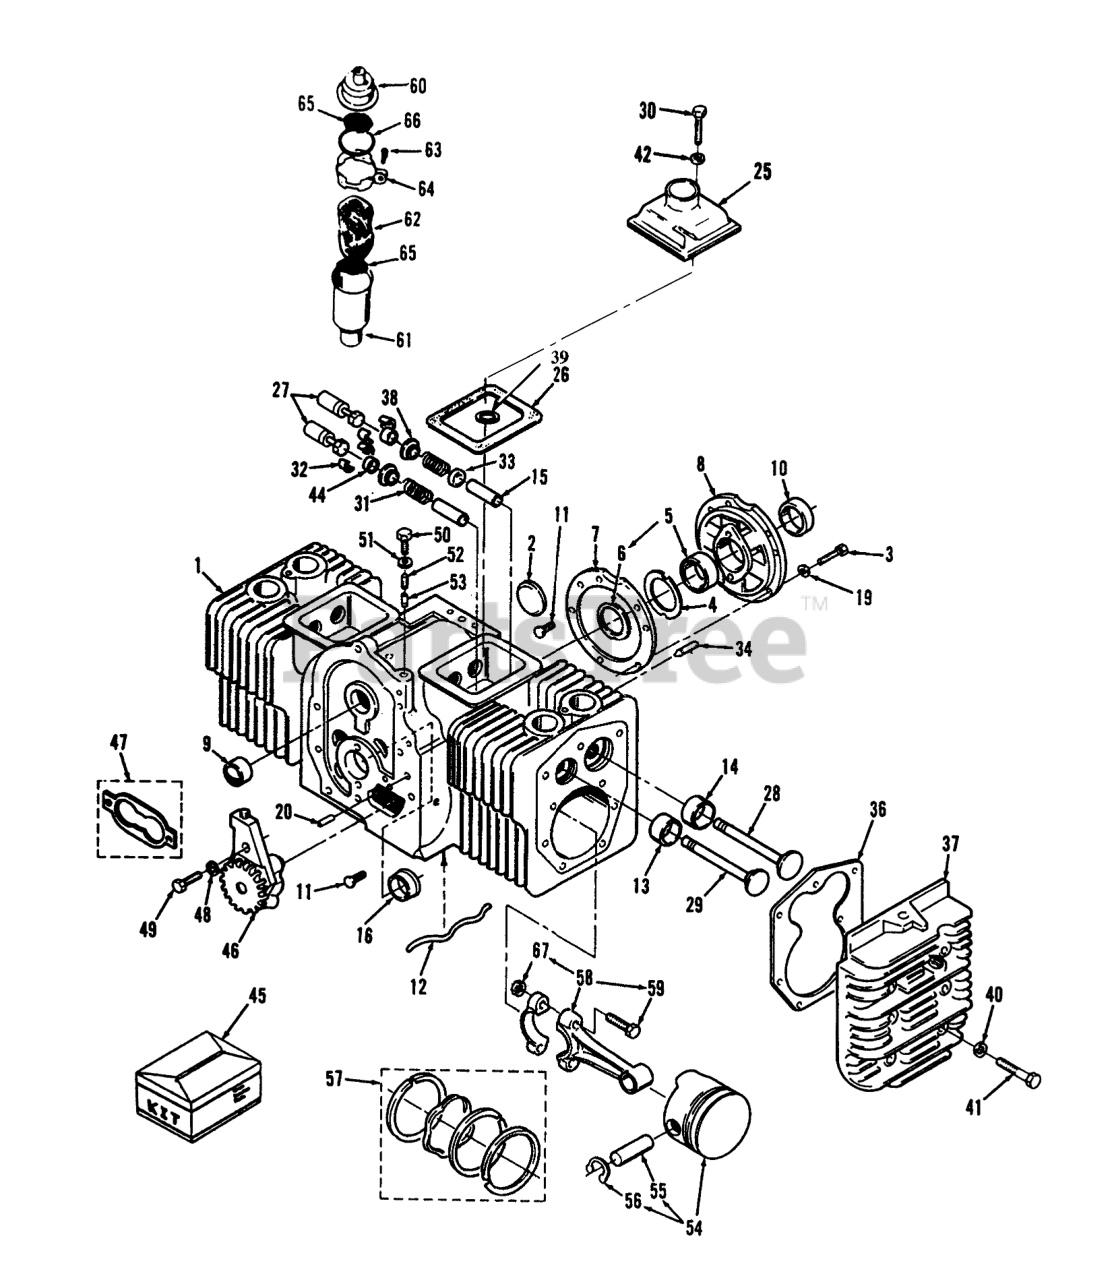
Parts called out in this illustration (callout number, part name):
1	CYLINDER BLOCK
2	Plug
3	Bolt 3/8-16x 1-1/4
5	Bearing-Crankshaft, Rear(Includes Thrust Washer)
6	Thrust Washer
7	GASKET
8	PLATE-BEARING, REAR
9	Camshaft Brg
10	Oil Seal
11	Screw
12	Oil Tube
13	Insert-Valve Seat, Exhaust
14	Insert-Valve Seat, Intake
15	Guide-ExhaustValve
16	Bearing-Crankshaft, Front,Flanged
19	Washer
20	Pin
25	Cover-Valve
26	GASKET
27	Tappet-Valve
28	Intake Valve
29	Exhaust Valve
30	HHCS 1/4-20 X 1 3/4
31	Spring
32	VALVE SPRING LOCK
33	Seal
34	Screw
36	Gasket
37	HOUSING CYL RH
38	Washer
39	Washer
40	Washer
41	Bolt
42	Washer
44	VALVE CAP
45	Kit-Gasket
46	Oil Pump
47	GASKET KIT
48	Washer
49	SCREW - CAP HEX HEAD
50	Bolt
51	Washer
52	Spring
53	Piunger
54	Piston (Includes Pin & Retaining Rings)
55	Pin-Piston
56	Retaining Ring
57	Kit-Ring, Piston
58	Rod-Connecting (Includes Bolt & Nut)
59	Rod Bolt
60	BREATHER-CAP AND VALVE
61	TUBE-BREATHER
62	FILTER
63	SCREW-TAPPING, ROUND HEAD
64	Clamp
65	SCREEN-BREATHER TUBE
66	SEAL - O-RING
67	Nut
